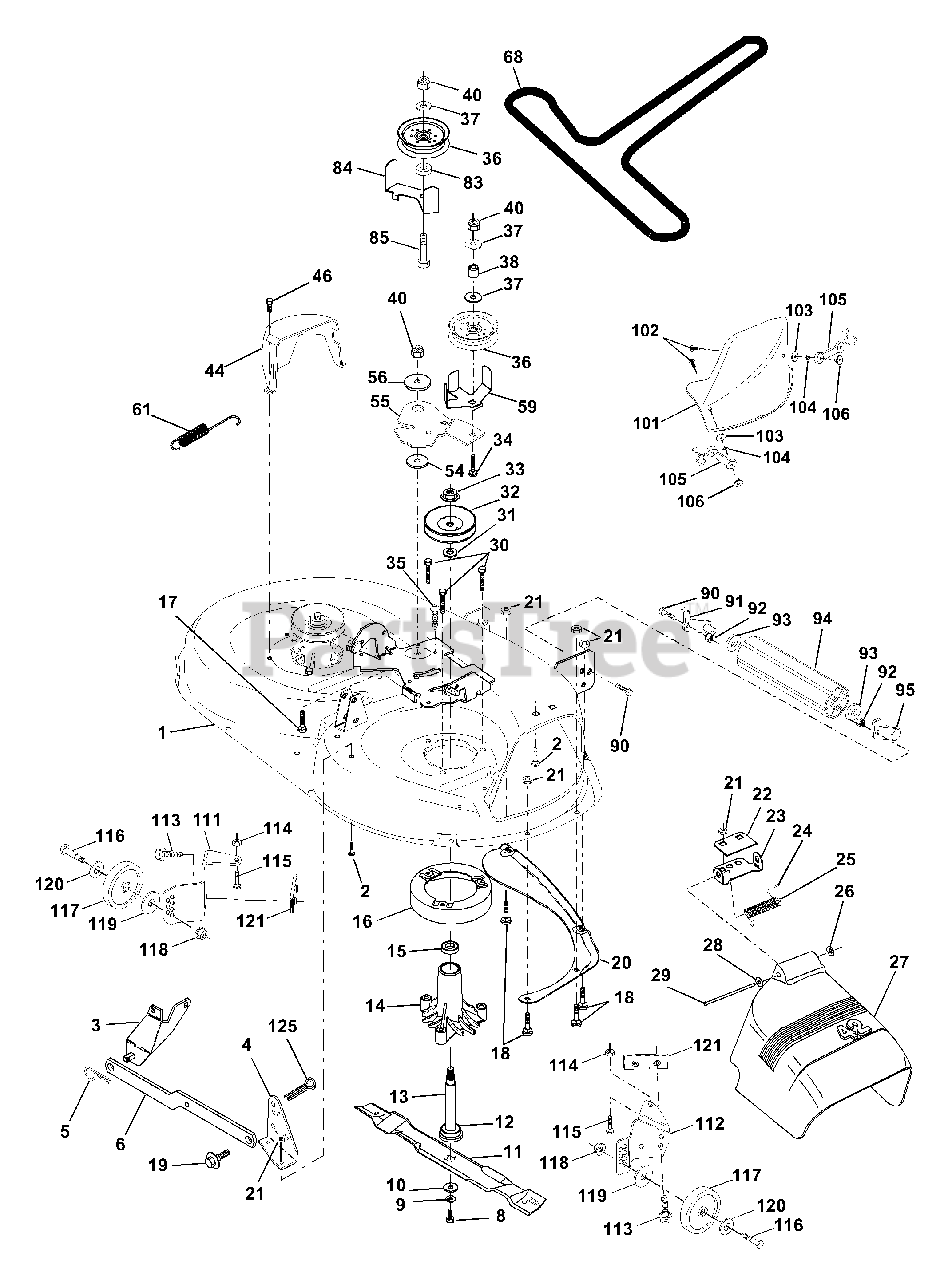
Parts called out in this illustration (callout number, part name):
1	Deck Asm MWR 42"weldment
2	Bolt Rdhd Sqnk 5/16-18unc X3/4
3	Bracket Asm Fr Sway Bar 38/42
4	Bracket Asm Deck 42"sway Bar
5	Retainer Spring
6	Arm Suspension Rear
8	Bolt 3/8-24x1 25 Gr8 Patched
9	Washer Lock Hvy 3/8 Unplated
10	Washer Hard Blade Mower Vented
11	Blade Mower Mulching 42"
12	Bearing Ball #6204 (Mandrel)
13	Shaft Asm W/lower Bearing
14	Housing Mandrel Vented(machd)
15	Bearing Ball Mandrel
16	Stripper Mower Vented
17	Bolt Carriage 3/8-16 X 2-1/4
18	Bolt Carr 5/16-18 X 5/8
19	Bolt Shoulder
20	Baffle Vortex 42
21	Nut Crown Lock 5/16-18
22	Stiffener Bracket 42"deck
23	Bracket Deflector Mower 42"
24	Cap Sleeve 80x 112 Blk Mower
25	Spring Torsion Deflector 2 52
26	Nut Push Phos & Oil
27	Shield Deflector Mower 42" Blk
28	Washer 11/32 X 5/8 X 16 Ga
29	Rod Hinge 42"6 75 Wlg
30	Screw Thdrol Hex Hd Zinc Mwr.
31	Washer Spacer Mower Vented
32	Pulley Mandrel 42"
33	Nut 9/16top Lock Flng Cntr
34	Bolt Rdhd 3/8-16uncx2-3/4 Gr5
35	Fastner Christmas Tree
36	Pulley Idler Flat 3 060
37	Washer 13/32 X 13/16 X 16 Ga
38	Spacer Spring Stop Idler
40	Nut Crownlock 3/8-16 Unc
44	Guard Mandrel LH Black
46	Screw Thdrol 1/4-20x5/8
54	Washer Hardened
55	Arm Idler 42"mower LT/YT
56	Spacer Retainer Pm Mower
59	Guard, Belt
61	Spring Ext. Elect
68	V-Belt Mower
83	Washer Sintered
84	Keeper Belt Idler Fixed
85	Bolt Carriage 3/8-16 x 2-1/4
90	Bolt Fin Hex 3/8-16unc X 1
91	Bracket Asm Noseroller LH
92	Nut Lock 3/8-16 Unc
93	Washer 17/32 X 7/8 X 16 Ga
94	Roller Nose 38 & 42
95	Bracket Asm Noseroller RH
101	Cover Mulching 42" Black
102	Screw
103	Washer #10
104	Washer Lock #10
105	Latch Asm. Bagger
106	Nut Weld
111	Bracket Wheel Gauge Lh 42" Deck
112	Bracket Wheel Gauge Rh 42" Deck
113	Screw Thdrol 5/16-18 x 3/4
114	Nut Keps 5/16-18 UNC
115	Bolt Carriage 5/16-Unc x 1/2
116	Bolt Shld "A" 2.41 "B" 1.66
117	Wheel Gauge blk. 4.93
118	Nut Centerlock 3/8-16 UNC
119	Washer 3/8 x 7/8 x 14 Ga.
120	Washer 17/32 x 15/16 x 12 Ga.
121	Bracket Extruded Gauge Wheel
125	Pin Cotter 1/4 x 1 Plated
